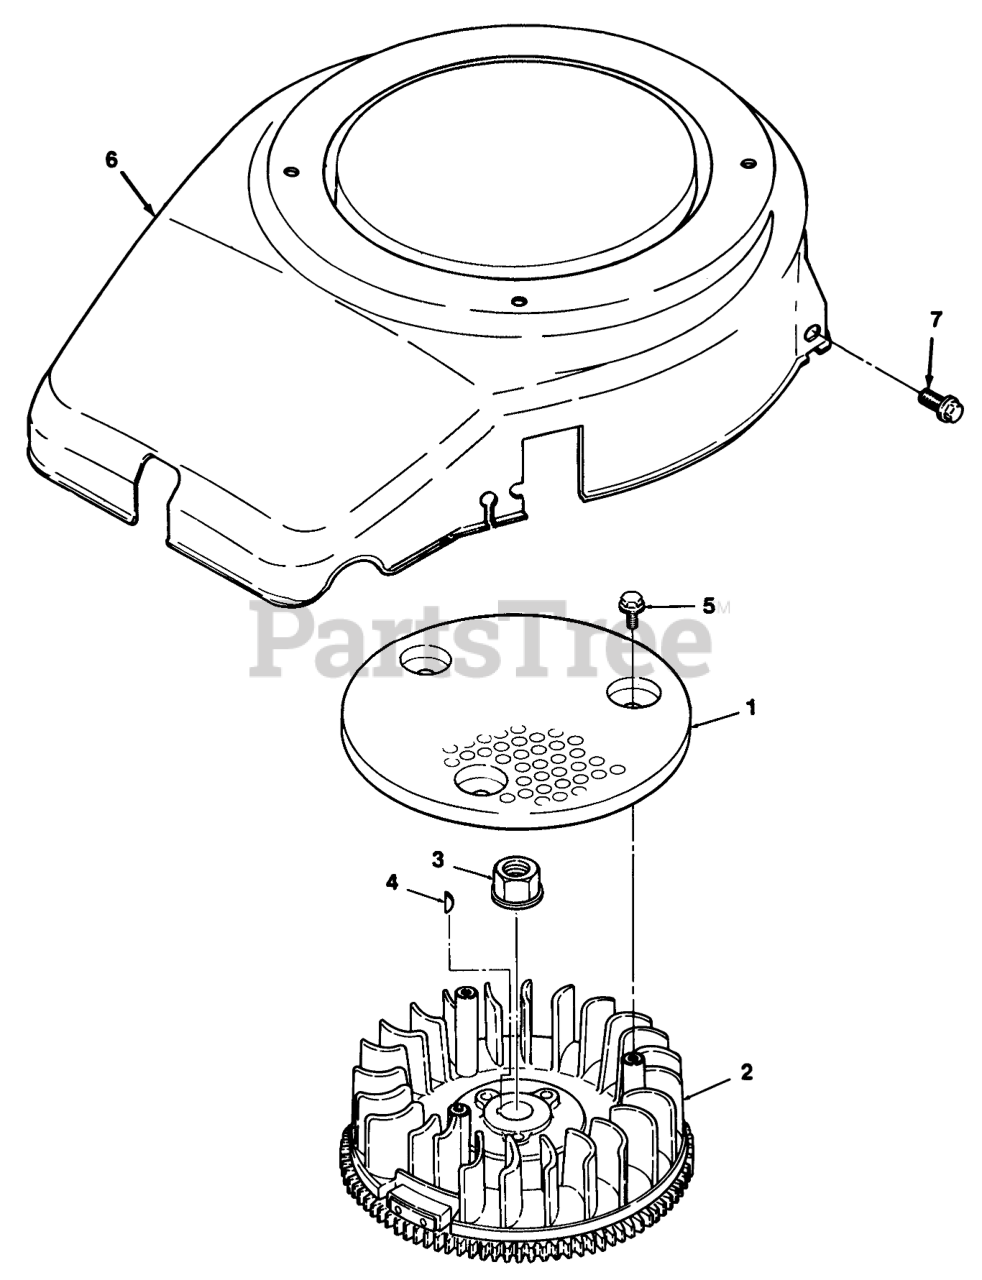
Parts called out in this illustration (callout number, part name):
1	SCREEN
2	WHL-ASS'Y BLOWER
3	NUT-FLANGE M18
5	HHCS-M6 X 30MM
6	HOUSING-BLOWER
7	BOLT-HHF M6 X 12MM
